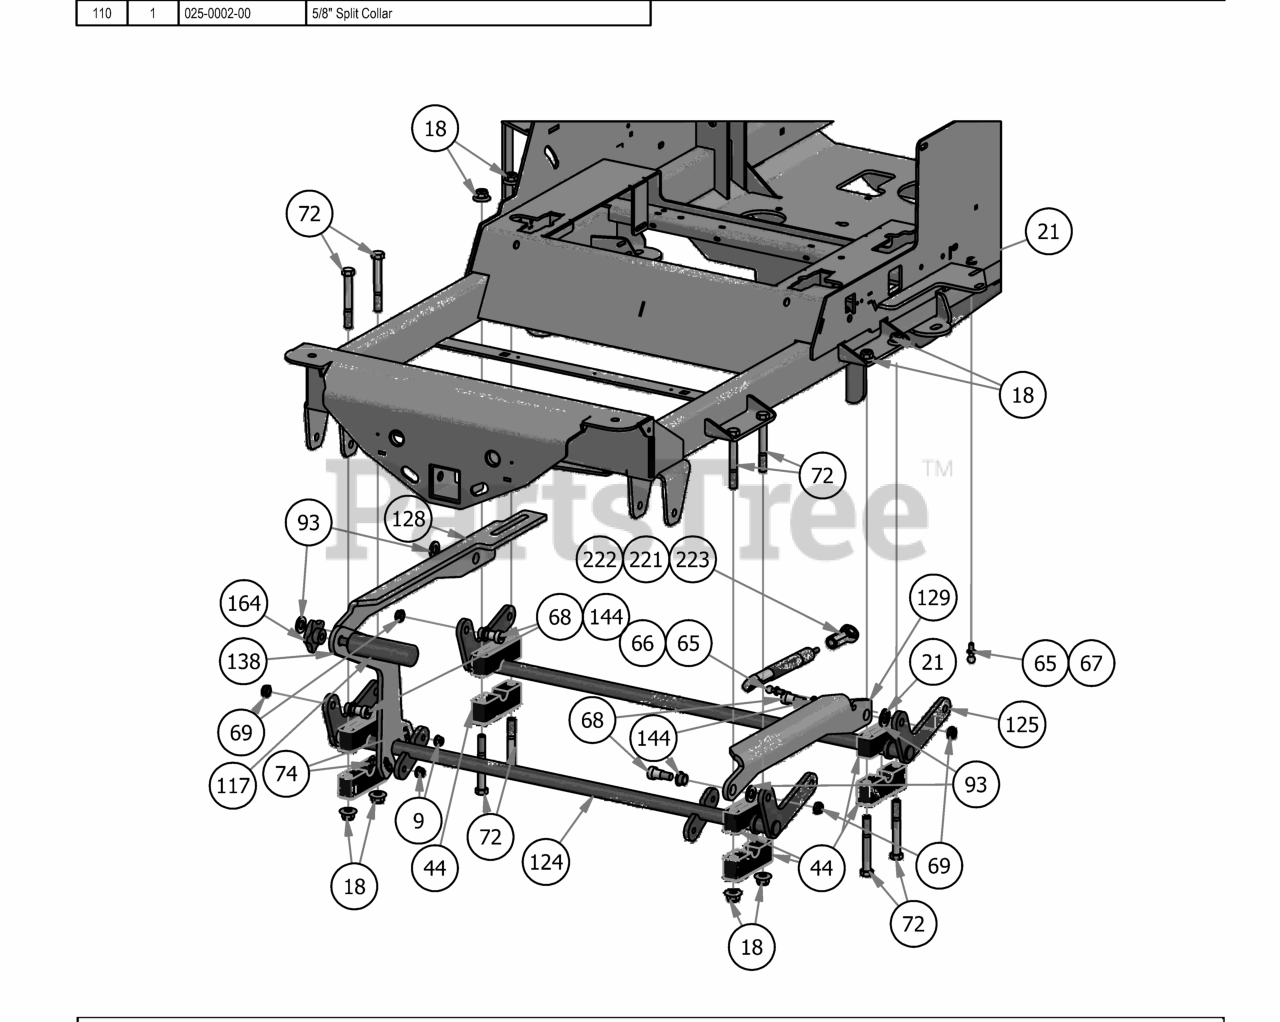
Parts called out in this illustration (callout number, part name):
9	3/8" Nylock Flange Nut
18	1/2-13 Nylon Flange Nut
21	5/16" Flange Nut
44	Pillow Block Assembly
65	13mm Damper Ball Stud-Steering
66	10mm Damper Ball Stud-Steering
67	10mm Damper Ball Stud-XP Linkage
68	5/8'' x 5/8'' Shoulder Bolt
69	1/2" Nylcock Nut (1/2 Jam)
72	1/2" x 4" Bolt (Grade 8)
74	3/8" x 1 1/4" Carriage Bolt
93	.630 ID Plastic Washer
117	Knurled Pedal
124	2019 Outlaw Actuator - Front
125	2019 Outlaw Actuator - Rear
128	2019 Actuator Linkage - Right
129	2019 Actuator Linkage - Left
138	Foot Lift Upright Lever
144	Bronze Bushing - SF - 2024-8
164	Foot Pedal Knob 1/2-13
204	2019 Veritical Suspension Frame
221	200 lb Gas Spring- 54" Deck outlaw
222	250lb Gas Spring - 61" Deck
223	300lb Gas Spring - 72" Deck
